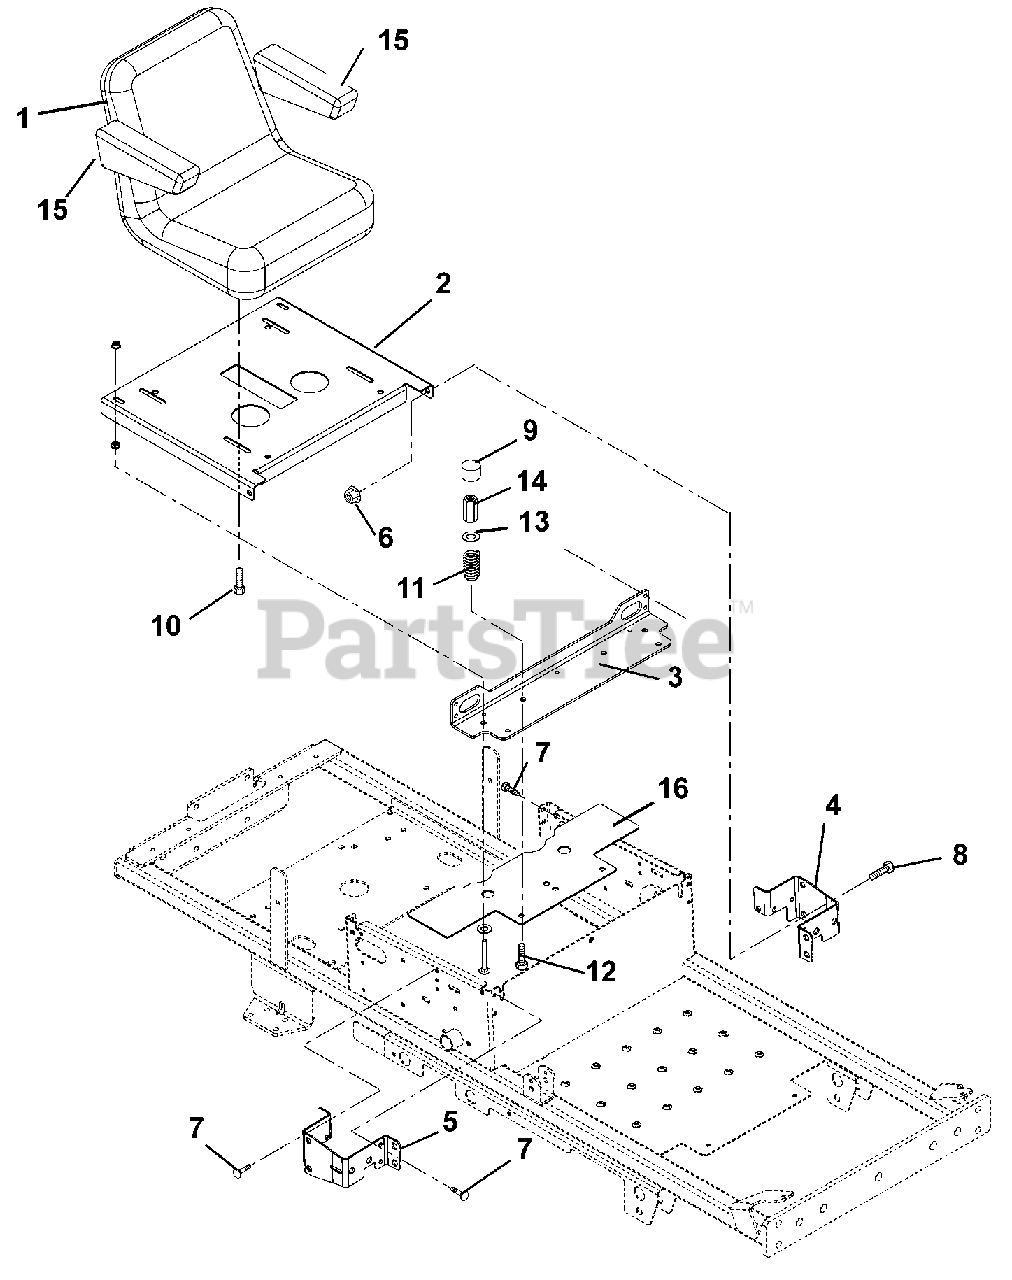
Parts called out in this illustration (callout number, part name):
1	Seat with Arm
2	Seat Plate
3	Bracket, Seat Spring
4	Bracket, RH Steering Stop
5	Bracket, LH Steering Stop
6	Nut, Locking Flange .38-16
7	Screw, Tapping .31-18 x .50
8	Bolt, Shoulder .375-16 x 1.50
10	Bolt-Hex .31-18 x 1.00 Grade 5
11	Spring, Seat
12	Bolt, Round Head Square Neck .31-18 x 1.50 Grade 5
13	Washer-Flat-Steel .328 x .87 x .179
14	Nut, Coupling 5/16-18 x 1 .75
15	Arm Rest
16	Guard, Finger
